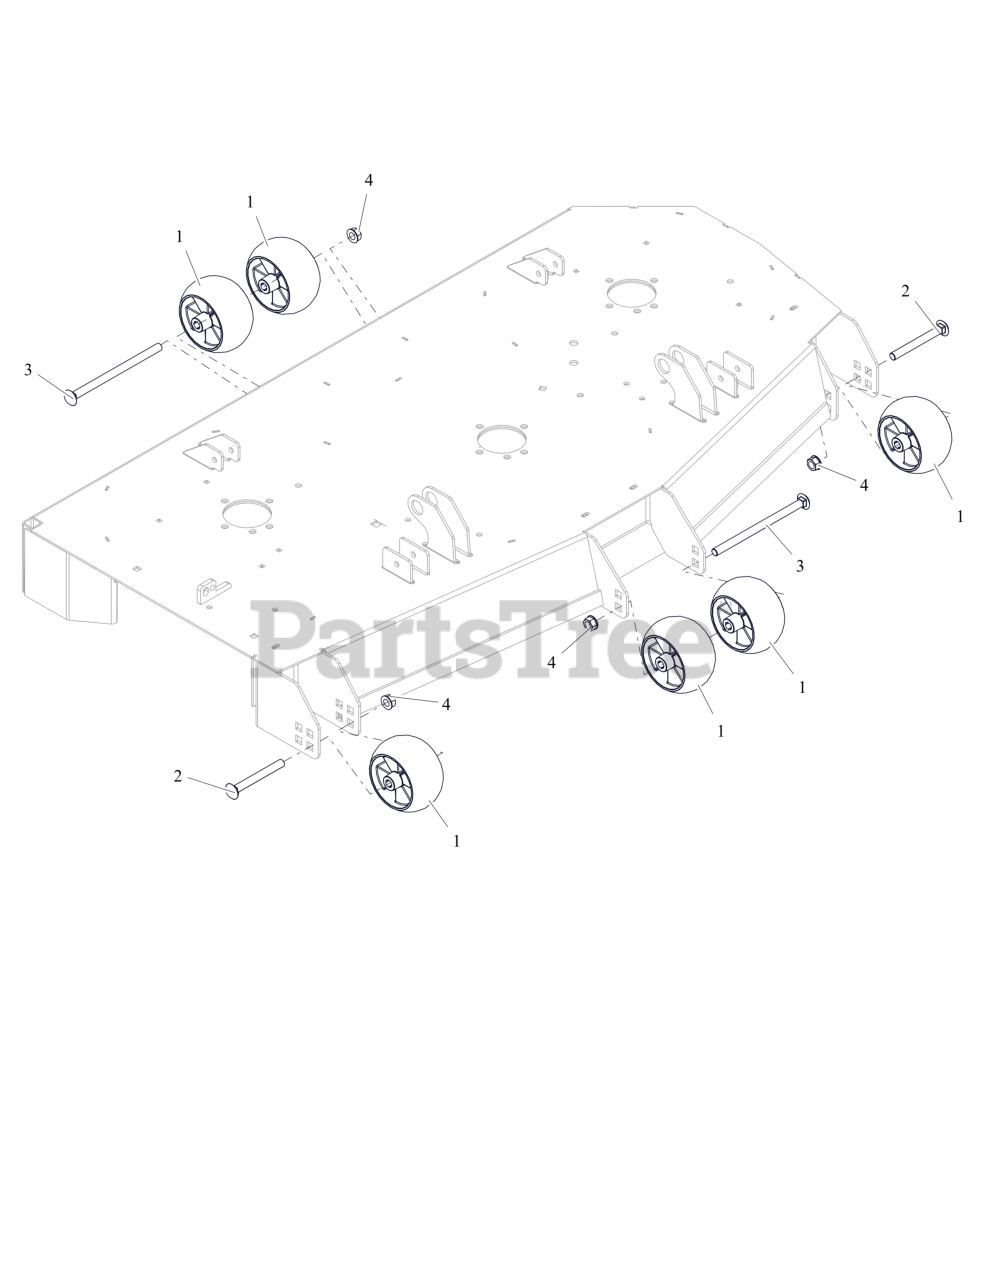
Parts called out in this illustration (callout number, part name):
1	WHEEL, ANTI SCALP - 5X3 CTR W/RIBS
2	BLT,RHSN .50-13X4.50 G5 ZCC
3	BTL,RHSN .500-13 X 8 G5 ZCC
4	NUT-LK-CTR-FLG .500-13 GG ZCC
